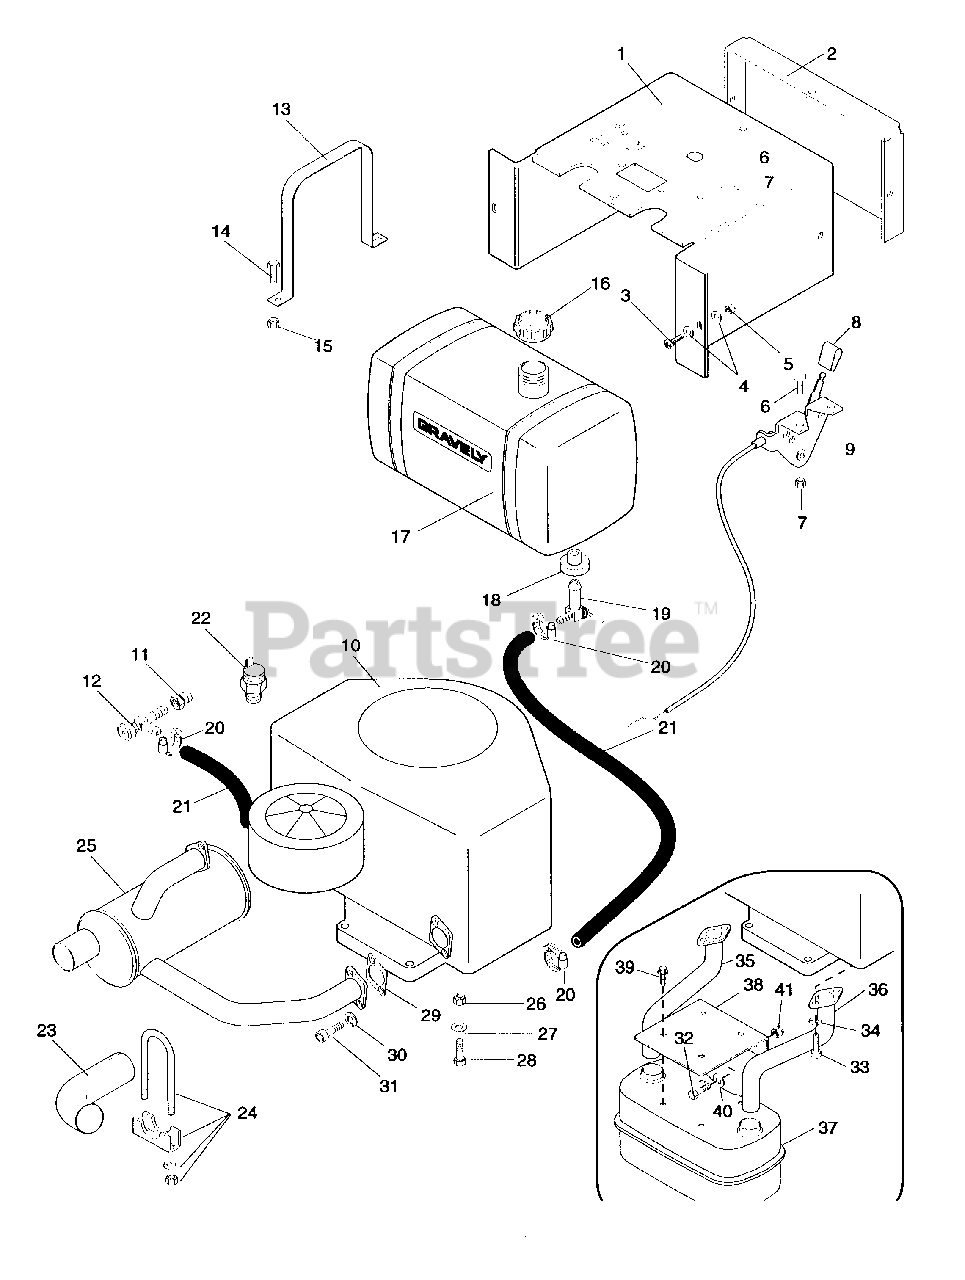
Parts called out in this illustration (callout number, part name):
1	Pnl, Silkscreen
2	Cvr, Instrument Panel
3	Scr - Mch .25 - 20 Pan Hd
4	Wshr - Fl - Stl .281 x .62 x .065 Pl
5	Nut - Lk - Nyl .250 - 20 Pl
6	Scr - Mch 10 - 32 x .50 Phd
7	Nut - Lk 10 - 32 Ny Pl
8	Knob
9	Asm, Choke Control
9	Asm, Throttle Control
10	Eng, 18 H.P. Magnum, PS-58550
10	Engine 16 HP B & S
11	Adapter, Oil Drain
12	Cock, Oil Drain
13	Strp, Fuel Tank
14	Blt - Hex .25 - 20 x .63
15	Nut - Lk - Nyl .250 - 20 Pl
16	Cap, Fuel Tank
17	Tank, Fuel Gravely Pro
18	Bushing
19	Valve, Ball Shut - Off
20	Hose Clamp
21	Gas Line - Bulk
22	Switch, Pressure
23	Deflector, Exhaust
24	Clamp, U 1.75
25	Muffler
26	Nut - Lk - Nyl .312 - 18 Pl
27	Wshr - Fl - Stl .344 x .66 x .065
28	Blt - Hex .31 - 18 x 1.50 Pl Gr 5
29	Gasket, Exhaust
30	Wshr - Lock .313 x .078 Pl
31	Scr - Cap .31 - 18 x .75 S/HD
32	Blt-Hex .38-16 x 1.50 Pl Gr 5
33	Scr-Skh M8 x 1.25 x 20MM Pl
34	Wshr-Lock .313 x .078 Pl
35	Headpipe, Nelson Q-33477, 16 B/S
36	Headpipe, Nelson Q-33476, 16 B/S
37	Muffler, Nelson #24392-N
38	Brk, Muffler, B/S V
39	Scr-Tap 12-24 x .75 Hwh Pl Tr
40	Wshr-Fl-Stl .438 x 1.0 x .083 Pl
41	Nut-Lk-Nyl .375-16 Pl
